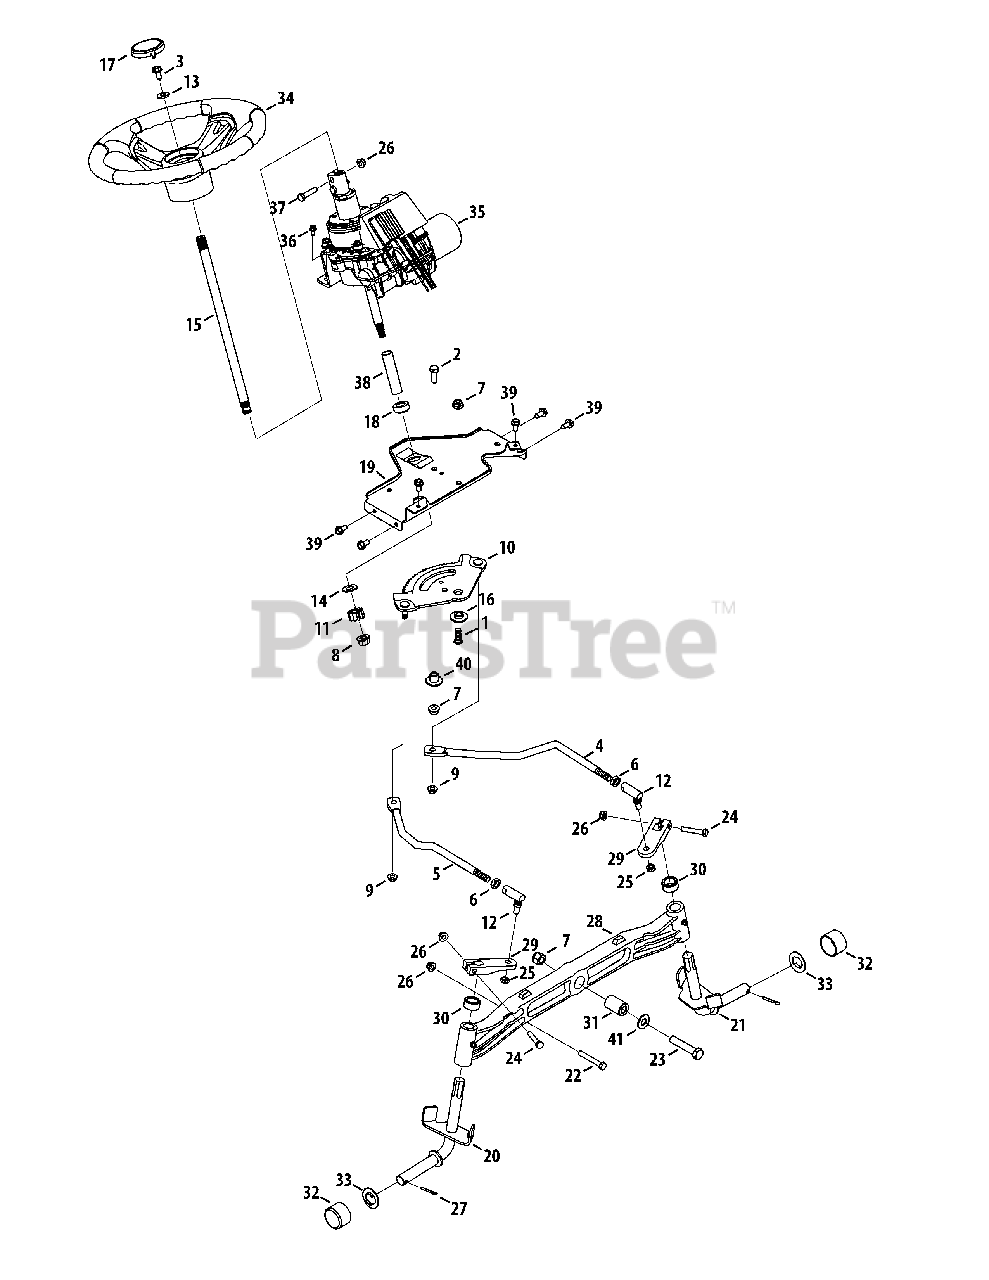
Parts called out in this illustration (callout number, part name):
1	Hex Screw, 3/8-16, 1.00, Gr5, Spec
2	Hex Screw, 3/8-16, 1.25, Gr5
3	Hex Screw, 5/16-18, .875, Gr5, Lock
4	Link, Drag LH
5	Link, Drag RH
6	Nut, Jam, 7/16-20, Gr2
7	Nut, Flange Lock, 3/8-16, Grf,
8	Nut, Flange Lock, 7/16-20, Grb, Lock
9	Nut, Flange Lock, 5/16-18, Gr5, Sd Lk
10	Gear, Steering
11	Gear, Pinion, Steering
12	Ball Joint, 7/16-20, Lock
13	Washer, Flat, .406 x .875 x .105
14	Washer, Flat, .51 x 1.12 x .06
15	Shaft, Steering, .625 OD x 14, Cub
16	Spacer, Shoulder, .385x 1.25 x .3025
17	Cover, Steering Wheel, Cub Cadet
18	Bearing, Flange, Hex 5/8 Pm
19	Bracket, Support, Steering
20	Axle Ass’y, RH .750 Dia.
21	Axle Ass’y, LH .750 Dia.
22	Hex Screw, 5/16-18, 2.25, Gr5, Std
23	Hex Screw, 3/8-16, 2.50, Gr5, Std
24	Hex Screw, 5/16-18, 1.75, Gr5, Std
25	Nut, Hex Lock, 3/8-24, Grb
26	Nut, Flange Lock, 5/16-18, Grf
27	Pin, Cotter, 5/32, 1.25
28	Axle, Pivot Bar, Cast
29	Steering, Block
30	Spacer, .71 ID x .125 OD x .56
31	Spacer, .385 x 1.00 x 1.5075
32	Cap, Bumper
33	Washer, Flat, .350 x 1.559 x .062
34	Wheel, Steering, 3 Spoke, Softgrip
35	Transmission Assembly, EPS, Steering
36	Screw, Self-tapping, 1/4-20 x .625
37	Hex Screw, 5/16-18 x 1.375, Gr5, Std
38	Spacer, .625 x .750 x 3.11
39	Screw, Self-tapping, 5/16-18, .750
40	Shoulder Spacer, .385 x 1.25 x .6525
41	Flat Washer, .406 x .875 x .059
